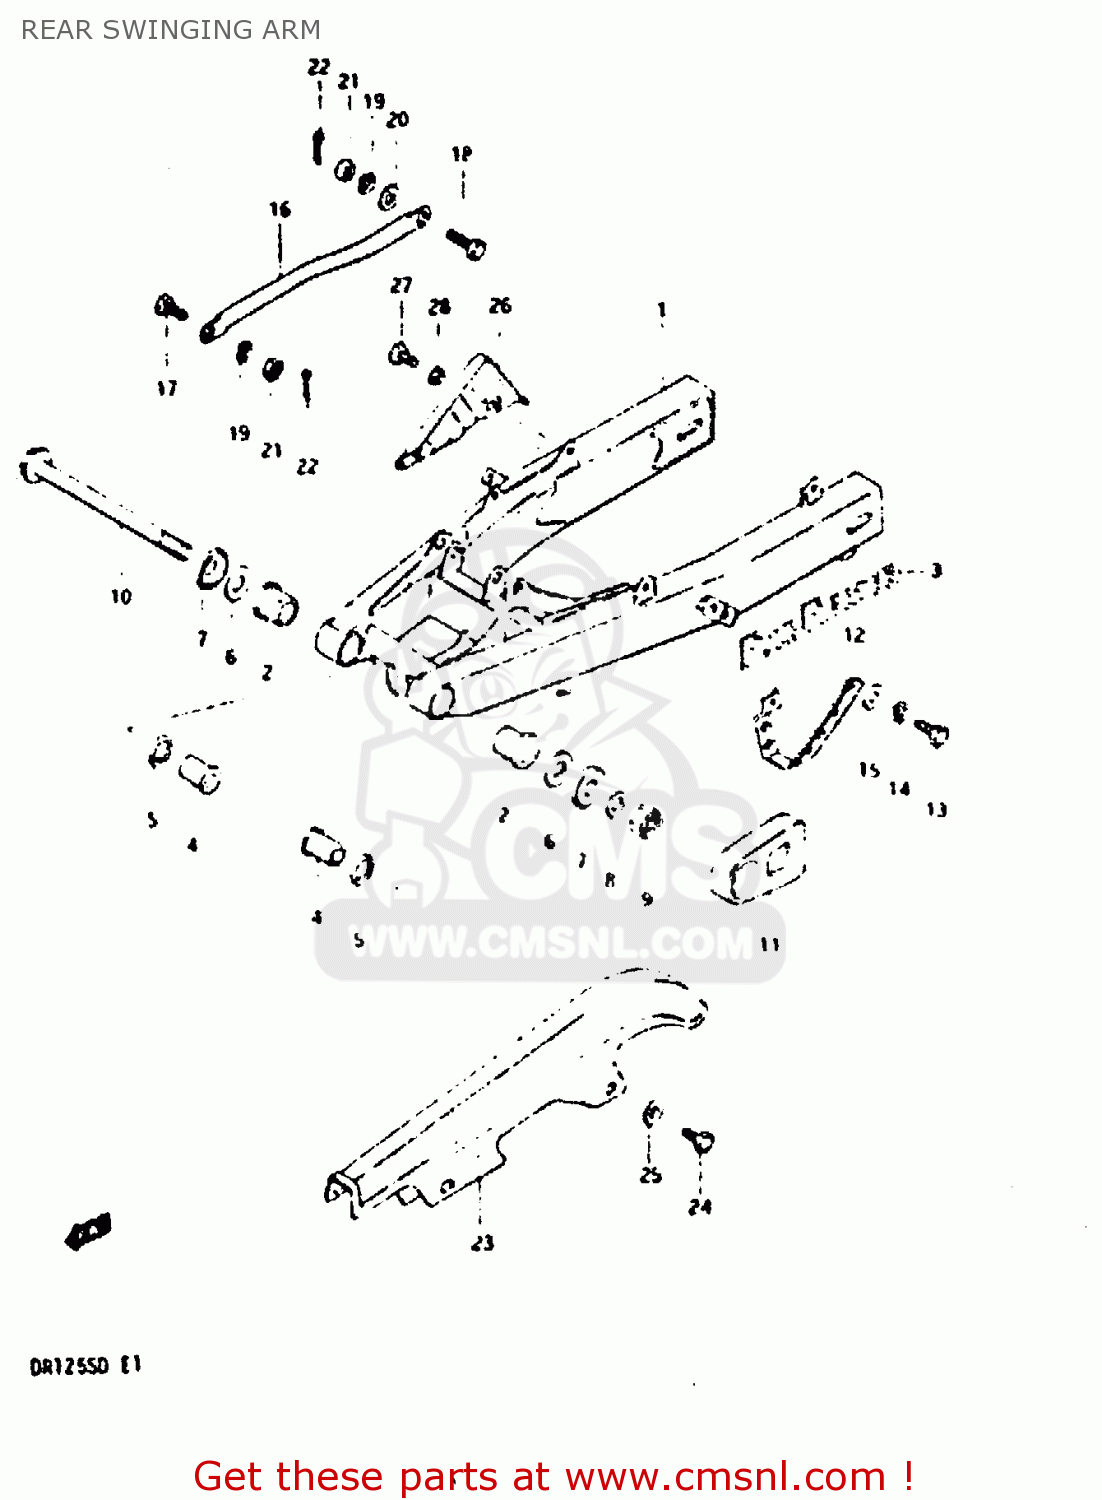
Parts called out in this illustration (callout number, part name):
1	SWING ARM ASSEMBLY,REAR
2	BUSHING,REAR SWING ARM PIVOT
3	EMBLEM
4	SPACER,REAR SWING ARM PIVOT
5	SEAL,OIL(20X27X5)
6	WASHER
7	CVR,RR SWGARM DUST SEAL(OD:40)
8	WASHER
9	NUT 14MM
10	SHAFT,REAR SWING ARM
11	BUFFER,CHAIN TOUCH DEFENSE
12	GUIDE,CHAIN
13	BOLT 8X12
14	LOCK WASHER
15	WASHER
16	TORQUE LINK,REAR
17	BOLT(8X22)
18	BOLT(8X26.5)
19	LOCK WASHER
20	WASHER
21	NUT
22	PIN 20X20
23	CASE,CHAIN
24	BOLT 6X8
25	WASHER
26	GUARD,PILLION FOOT
27	BOLT 6X8
28	WASHER
